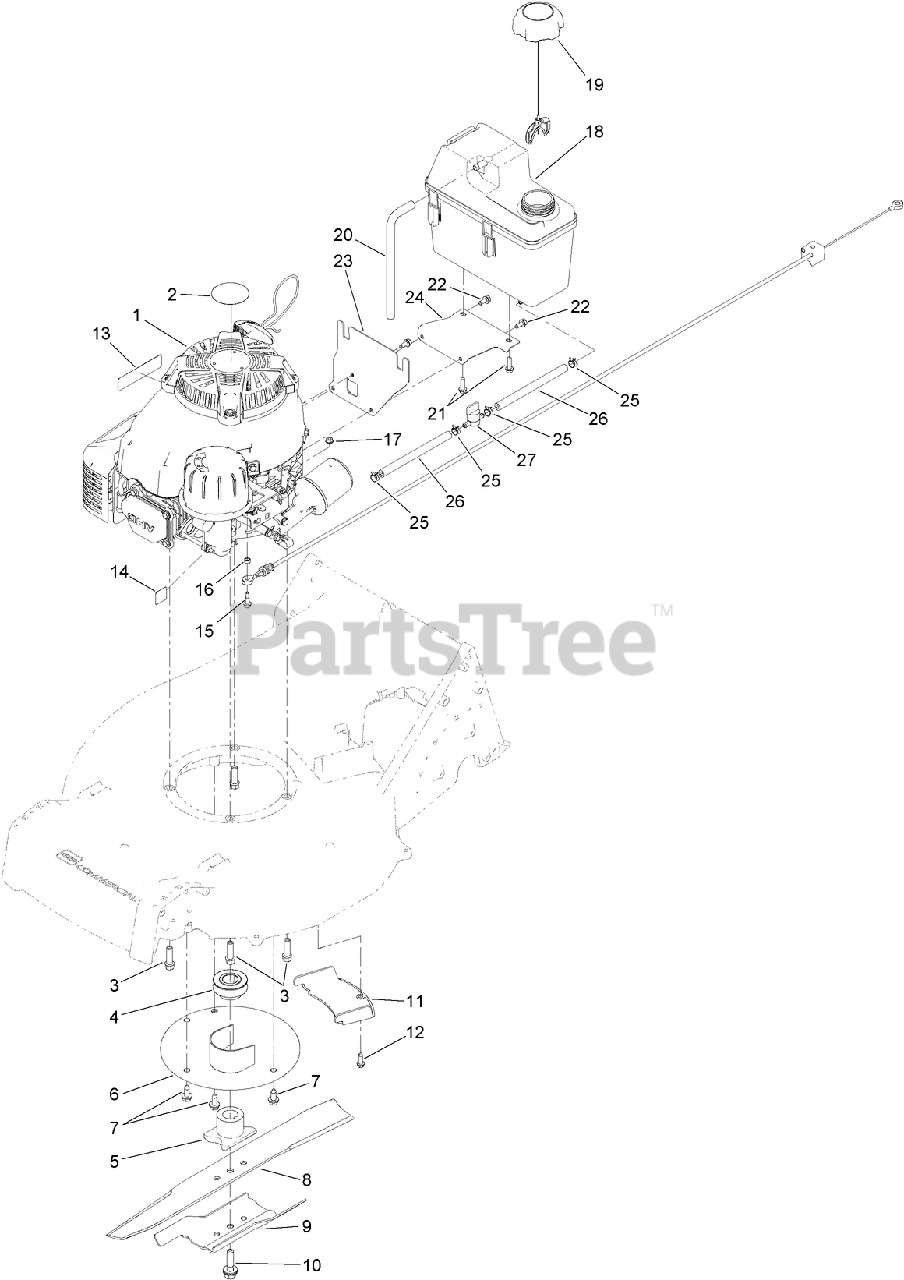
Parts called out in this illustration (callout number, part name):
1	ENGINE-KAWASAKI, FJ180V
3	SCREW-TAPTITE
4	PULLEY-DRIVER
5	DRIVER-BLADE
6	PROTECTOR-CRANKSHAFT
7	SCREW-HWHTF
8	BLADE-RECYCLING
9	ACCELERATOR-BLADE
10	BOLT-BLADE
11	COVER-BELT
12	SCREW-HWHTF
13	DECAL-ARRESTER, SPARK
14	DECAL-PRIMER
15	SCREW-SHOULDER
16	SPACER
17	NUT-LOCK, FLANGE
18	TANK-FUEL
19	CAP-FUEL
20	HOSE-VENT, CANISTER
21	SCREW-HWH
22	SCREW-HWH
23	BRACKET-TANK, MOUNTING
24	BRACKET-TANK, SUPPORT
25	CLAMP-HOSE
26	HOSE-FUEL
27	VALVE-FUEL
